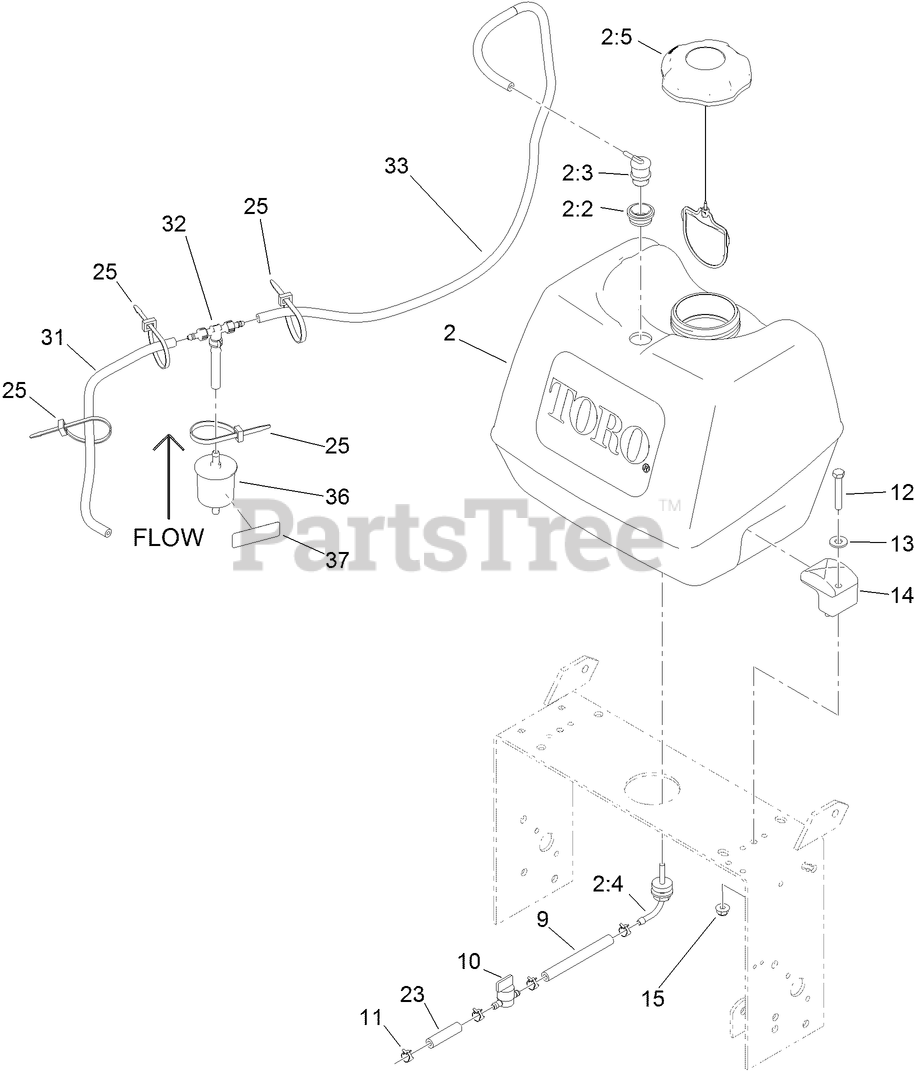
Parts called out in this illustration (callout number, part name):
2	FUEL TANK ASM
2:2	GROMMET
2:3	VALVE-ROLLOVER
2:4	FITTING-FUEL, BULKHEAD
2:5	CAP-FUEL, RATCHETING
9	HOSE-FUEL
10	VALVE-FUEL
11	CLAMP-HOSE
12	SCREW-HH
13	WASHER-FLAT
15	NUT-HF, NI
23	HOSE-FUEL
25	TIE-CABLE
31	HOSE-FUEL
32	TEE AND CHECK
33	HOSE-EMISSIONS
36	FILTER-FUEL
37	DECAL-FILTER, EMISSIONS
